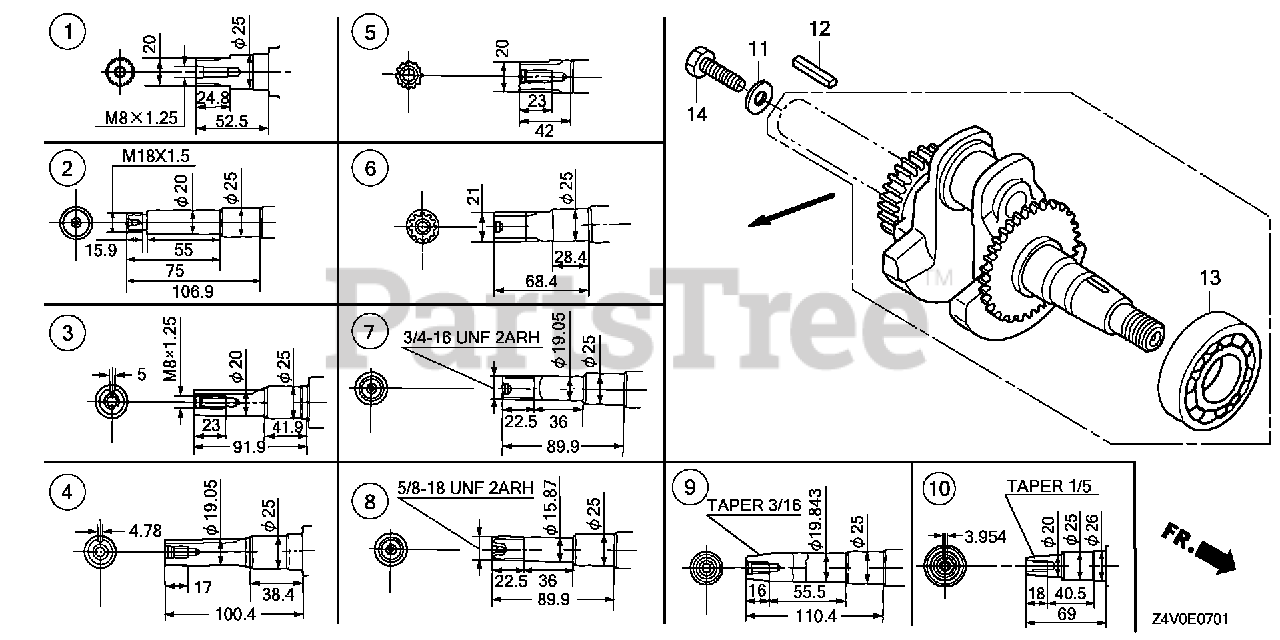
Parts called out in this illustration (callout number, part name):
8	CRANKSHAFT
13	BEARING, RADIAL BALL (6205)
13	BEARING, RADIAL BALL (6205) (NSK)
